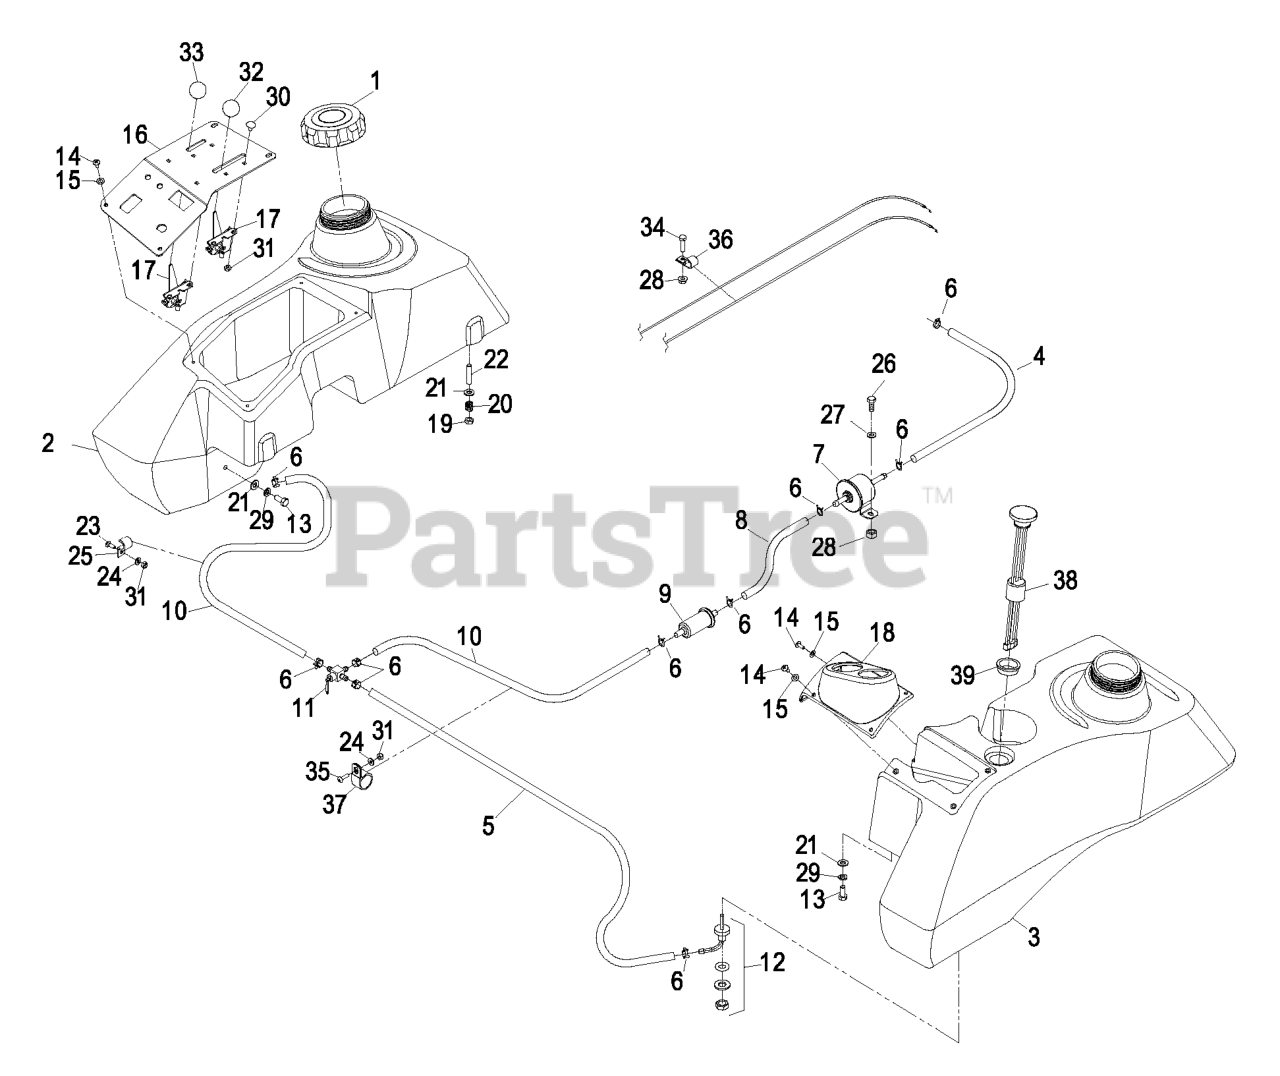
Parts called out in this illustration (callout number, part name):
3	ASM,FUEL TANK LH LC
4	HOSE-FUEL
5	HOSE-FUEL
7	P/N 49040-2065 Fuel Pump
8	HOSE-FUEL
9	P/N 49019-1055 Fuel Filter
11	VALVE-FUEL
12	FITTING-FUEL, BULKHEAD
13	SCREW-HH
14	SCREW-PTH
15	WASHER-SPRING
17	CABLE-THROTTLE
18	BEZEL, GAGE XP LH TANK
19	NUT-LOCK, NI
20	SPRING-TANK, FUEL
21	WASHER-PLAIN
22	STUD
23	BOLT-CARR
24	WASHER-FLAT
25	CLIP-HALF, LOOM
26	SCREW-HH
27	WASHER-FLAT
29	WASHER-LOCK
30	BOLT-CARR
31	NUT-LOCK, NI
32	KNOB-BALL
33	KNOB-BALL, BLACK
34	SCREW-HH
35	SCREW-HEAD, TRUSS
36	CLIP-LOOM
37	CLIP-LOOM
39	CONTACT ORDER SERVICES
